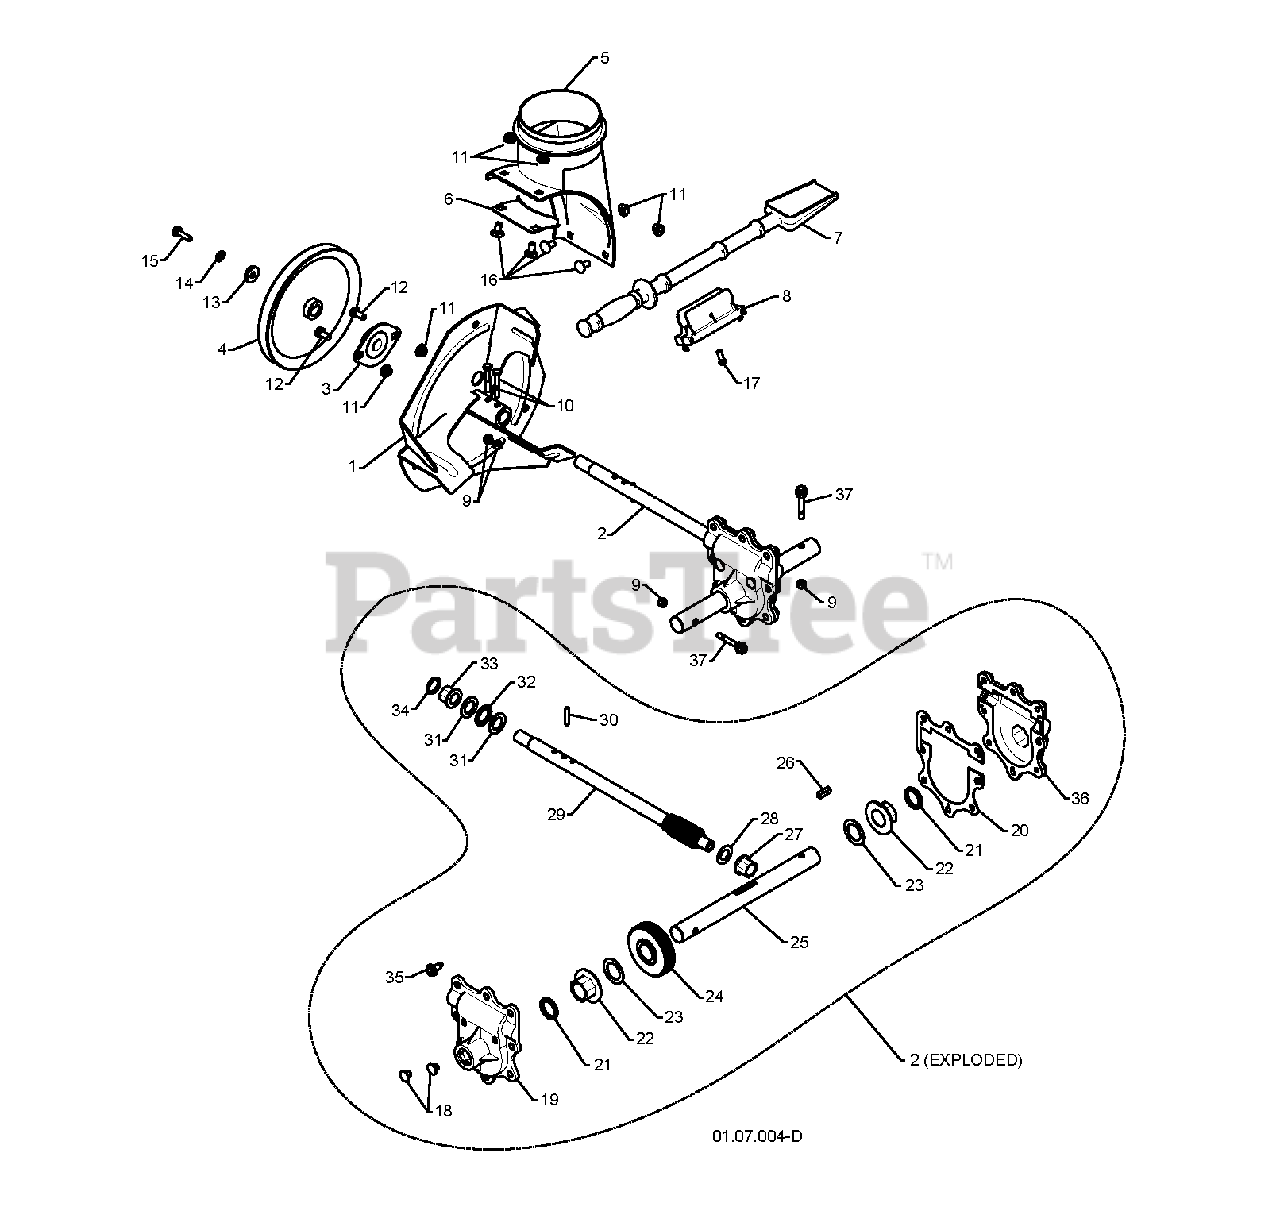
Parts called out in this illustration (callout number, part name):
1	IMPELLER ASSY
2	GEARBOX.ASSEMBLY.AUGER
3	BEARING FLANGE
4	PULLEY.IMPELLER
5	BASE DISCHARGE CHUTE
6	BRACKET, CORNER DISCHARGE
7	CLEAN OUT TOOL
8	CLIP.CLEANOUT.TOOL
9	LOCKNUT
10	SCREW.HEX.HD1/4-20X
11	NUTNYLOK.FLRANGE.5/16-18
12	BOLT, HEX HEAD 5/16-18
13	WASHER, FLAT
14	LOCKWASHER
15	CAPSCREW.HX.HD.5/16-18X1.00.NY
16	BOLT.CARRIAGE.5/16-18X
17	SCREW.HWH.13-16-5.8.BZP
18	CASE PLUG
19	GEARBOX HOUSING-RH
20	GEARBOX GASKET
21	OIL SEAL
22	FLANGE BUSHING-1"
23	WASHER TRUST 1"
24	WORM GEAR
25	AUGER SHAFT
26	KEY, SQUARE 1/4 X .875
27	FLANGE BUSHING-5/8
28	WASHER, THRUST 5/8
29	SHAFT, IMPELLER
30	PIN, ROLL 3/16 X 1-1/8
31	WASHER, THRUST 3/4
32	BEARING TRUST 3/4
33	BUSHING, FLANGE 3/4
35	HEX SCREW-5/16 X 3/4
36	GEARBOX HOUSING - LH
37	BOLT, SHOULDER SHEAR
